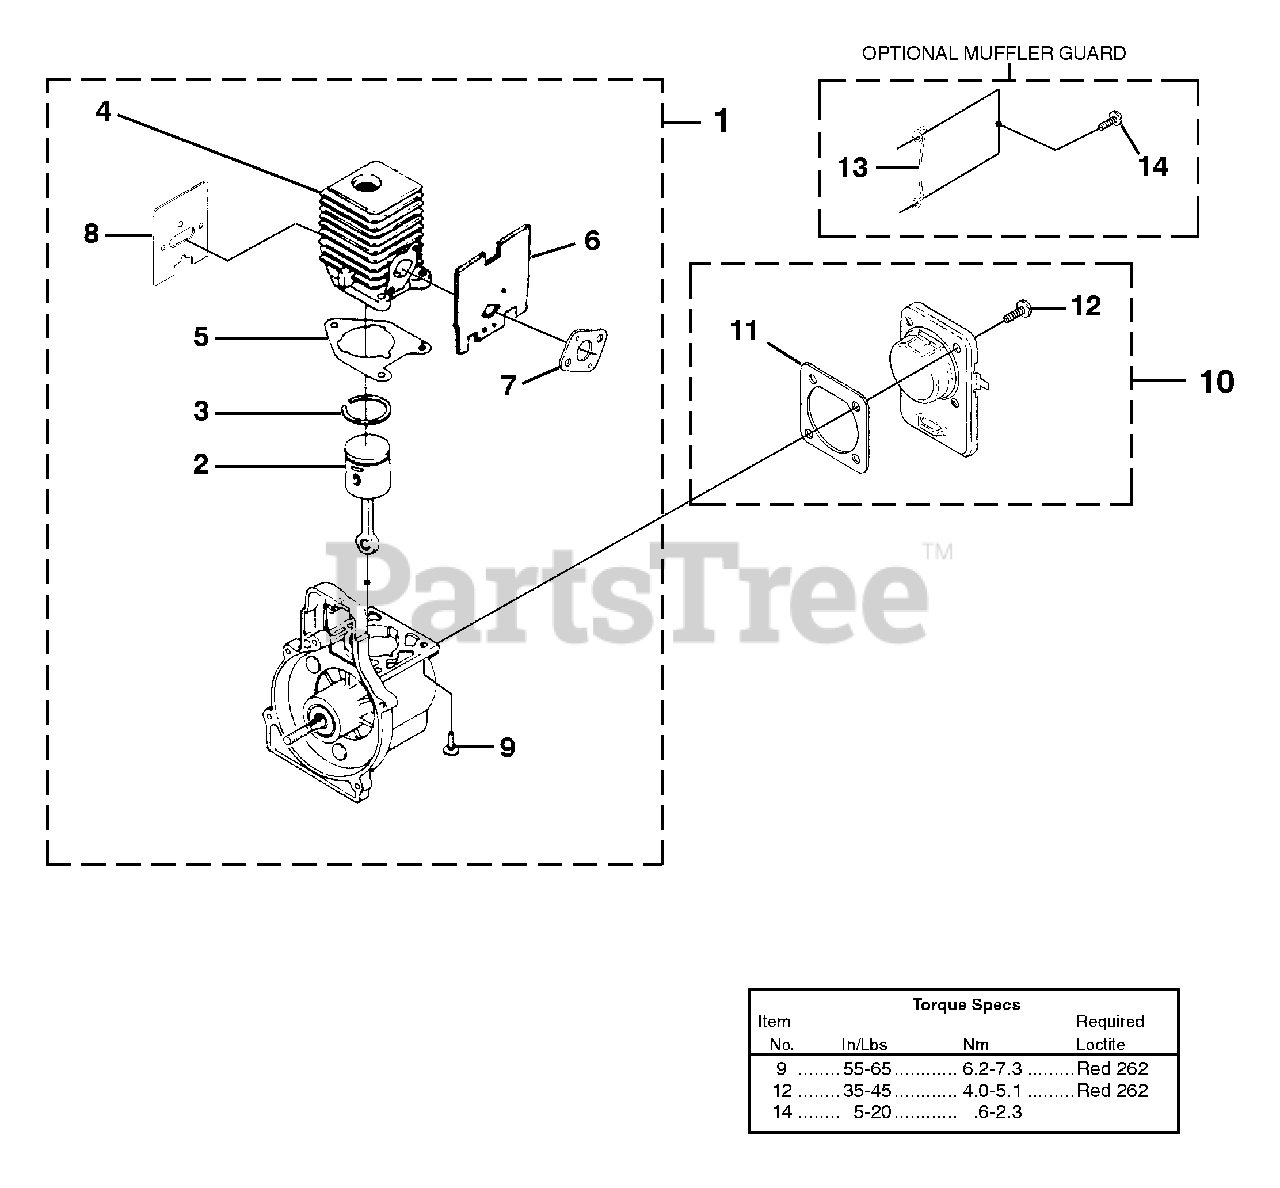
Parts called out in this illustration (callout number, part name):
1	SHORT BLOCK
2	PISTON & ROD ASSY.
3	RING-Piston
4	CYLINDER ASSY.
5	GASKET-Cylinder
6	GASKET-Heat Dam
7	GASKET-Carburetor
8	GASKET-Muffler
9	SCREW-Sems (12-24 X 3/4")
10	CRANKCASE COVER ASSEMBLY
11	GASKET-Crankcase Cover
12	SCREW-Sems (10-24 X 1/2")
13	MUFFLER GUARD
14	SCREW-Thread Forming (10-14 X 1/2")
